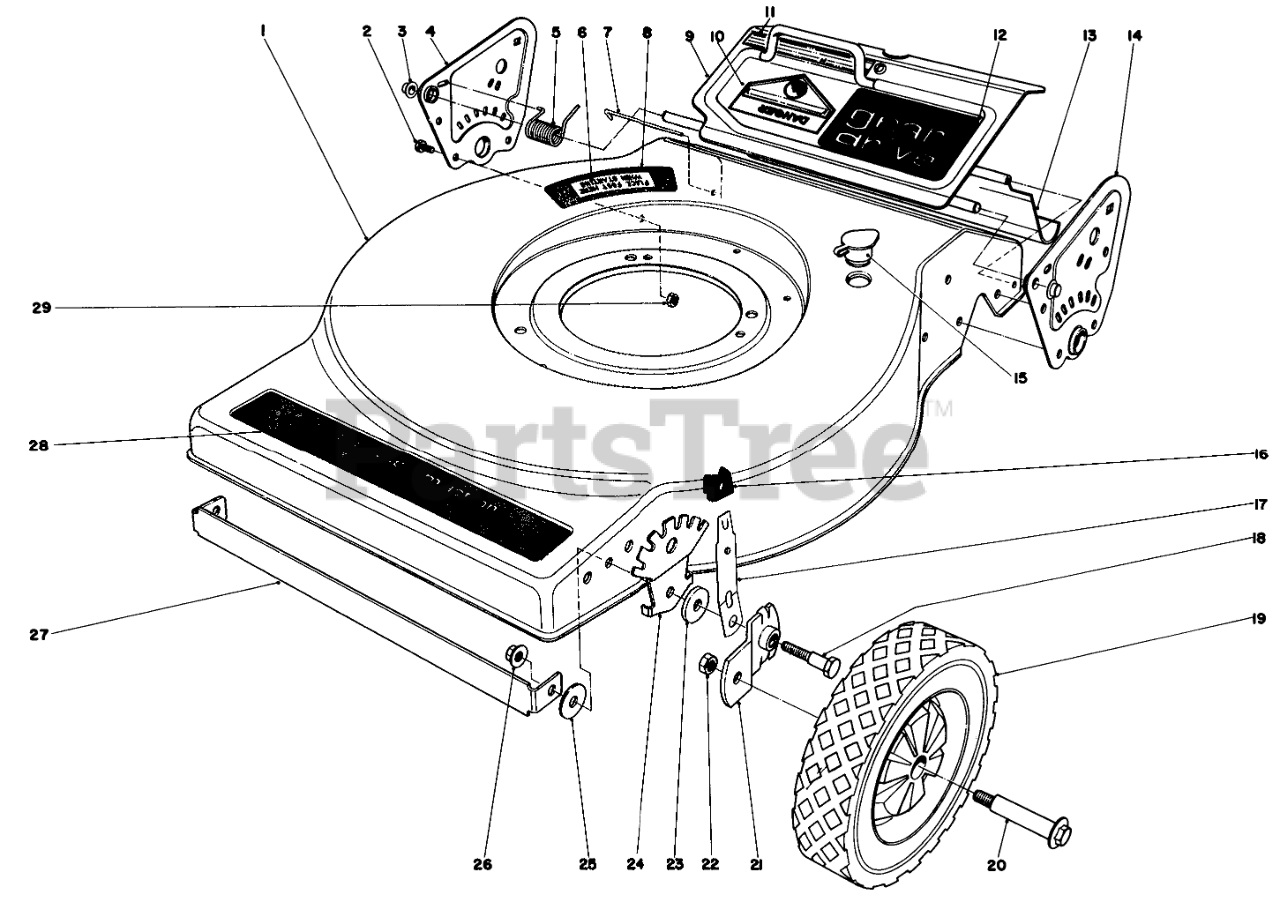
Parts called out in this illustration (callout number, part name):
1	Housing
2	SCREW-HH
3	RETAINER-PUSH ON
4	Side Plate R.H
5	TORSION SPRING
6	Decal Step Pad
7	SHIELD ROD
8	PAD STEP
9	Rear Door
10	DECAL-DANGER
11	Decal-Door
12	Decal-Door
13	SAF SHIELD REAR
14	Side Plate L.H.
15	WASHOUT PLUG
16	KNOB-ARM
17	SPRING ARM ASM
18	PIVOT SCREW
19	WHEEL TIRE ASM 8 IN
20	BOLT-WHEEL
21	PIVOT ARM ASM A
22	Nut
23	PIVOT WASHER
24	Quadrant
25	WASHER
27	DECK SUPPORT
28	Decal-Deck
29	NUT-LOCK, CONE
